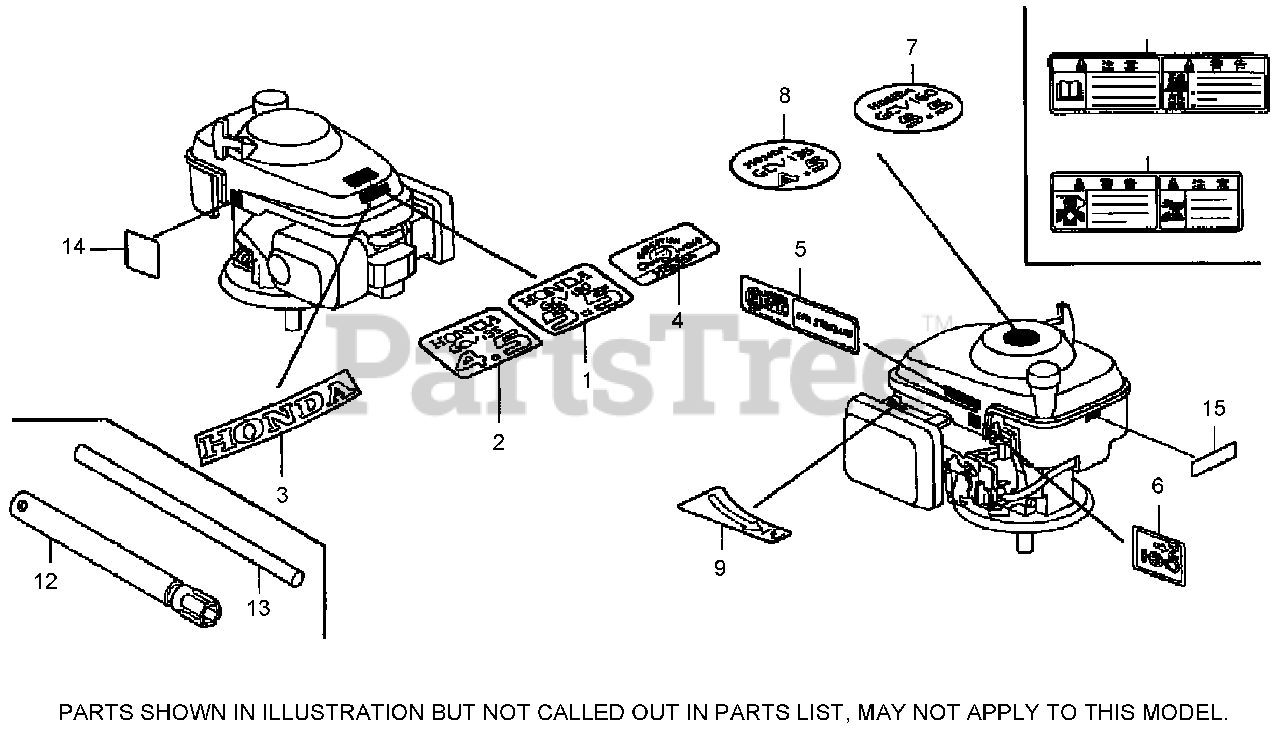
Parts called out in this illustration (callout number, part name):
1	EMBLEM (GCV160 5.5)
9	MARK, CHOKE INDICATION
15	MARK, TYPE (R3A1)
